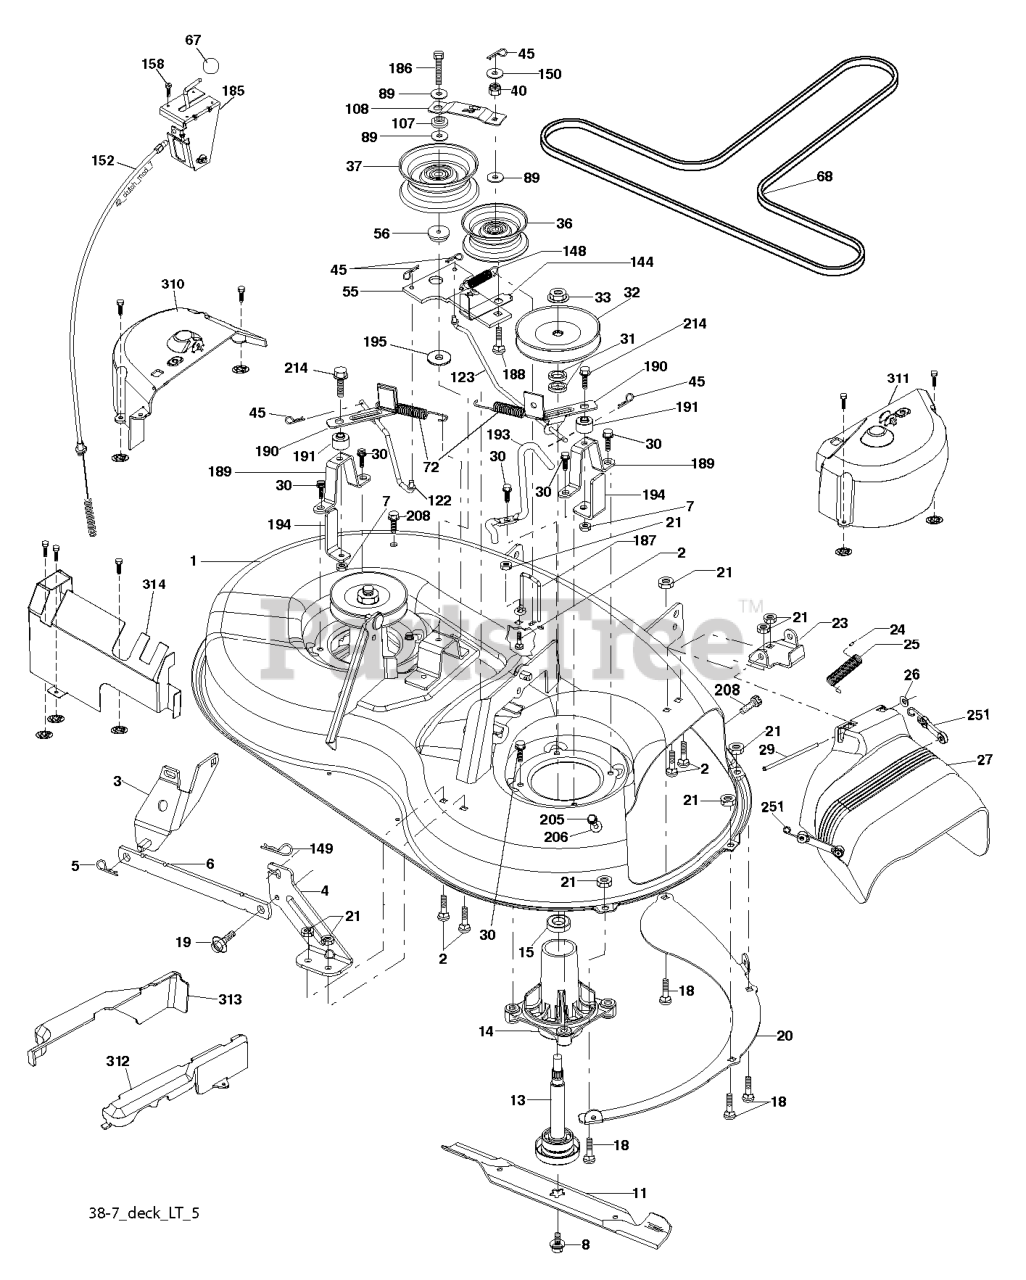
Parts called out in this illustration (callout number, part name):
2	VALVE STEM LT
3	TIRE HEAVY DUTY
4	TUBE.5.3/4.5/6
5	RIM ASM 6" FRONT SILVER
6	FITTING LT
7	BEARING T
8	RIM ASM 8" REAR SILVER
9	TIRE.TS.20X10-8
10	TUBE
11	CAP, AXLE BLK
